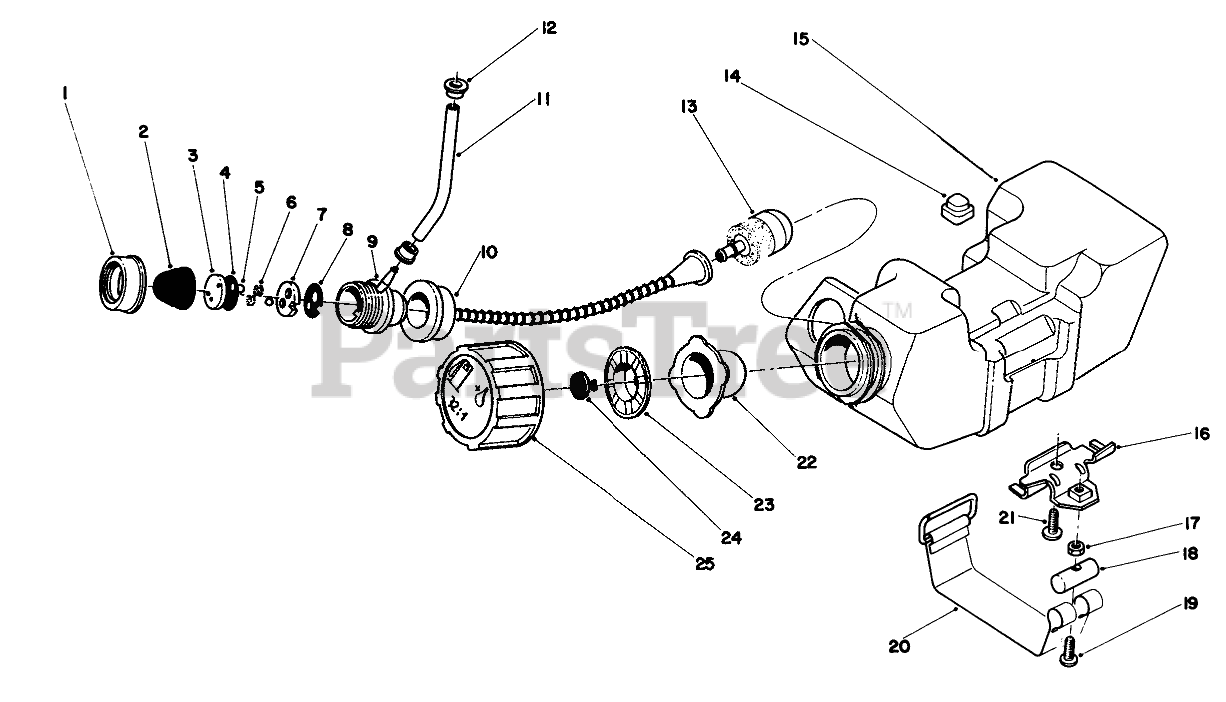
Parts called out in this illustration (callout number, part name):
1	PUMP CAP
3	SEAT VALVE
4	GASKET
6	SPONGE
7	SEAT VALVE
8	GASKET
9	Pump-Primer (Incl. Ref. #2-8)
10	HOSE, SUCTION
11	Tube-Fuel
13	FUEL FILTER
15	Fuel Tank Assembly (Incl. Ref. #1-10, 13, 21-24)
16	HANGER, TANK
19	Screw
20	BAND, TANK
21	Screw
22	GASKET - PACKING
23	HOLDER
24	BREATHER VALVE
25	TANK CAP
